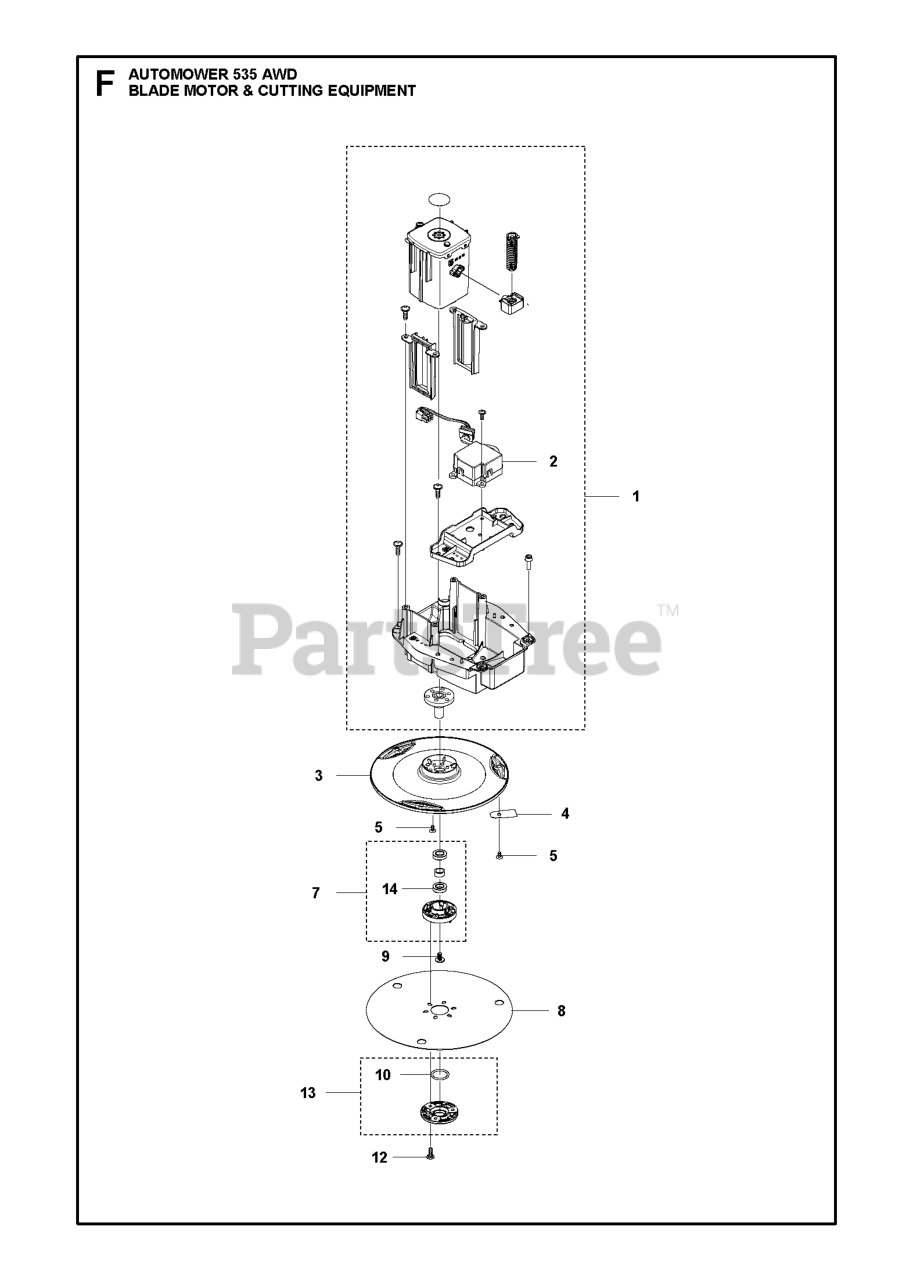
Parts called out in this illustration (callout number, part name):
3	GUARDS
4	HUS BLADE SET 300 PCS
4	HUS BLADE SET 9 PCS
4	HUS BLADE SET 45 PCS
5	SCREW HEXAGON SOCKET BUTTON HE
7	BEARING HOUSING ASSY
8	SKID PLATE
10	O-RING 20X2,5 MM
12	SCREW 14MM
13	COVER KIT BEARING
14	BALL BEARING 2 RS,TIGHT CLEAR
14	BALL BEARING BALL BEARING 535
